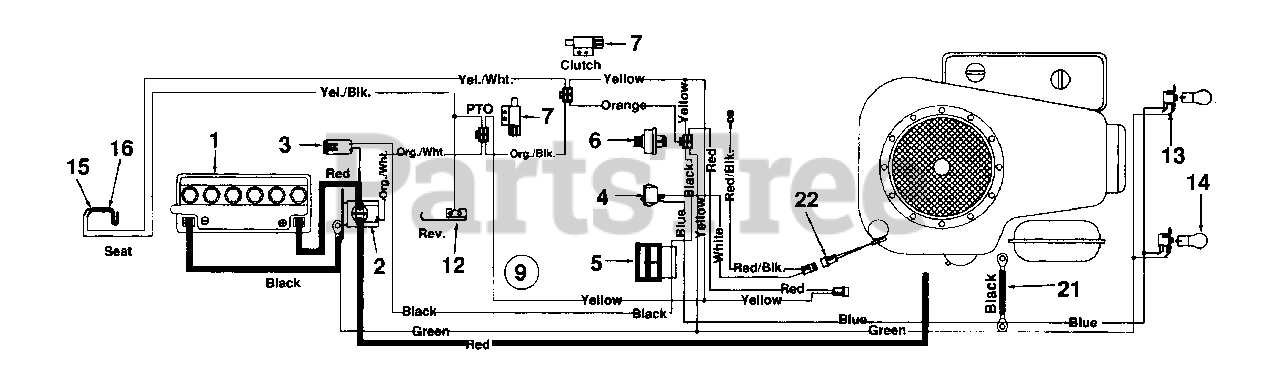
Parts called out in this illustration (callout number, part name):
1	Battery
2	Solenoid
3	Fuse 20 Amp
4	Light Switch
5	Ammeter
6	Ignition Switch
7	Safety Switch (Clutch)
9	Wire Harness
12	Safety Switch (Reverse)
13	Bulb Socket
14	Bulb
15	Safety Switch (Seat)
16	Safety Switch (Seat)
21	Ground Wire 7.5" Lg.
22	Harness Adapter
